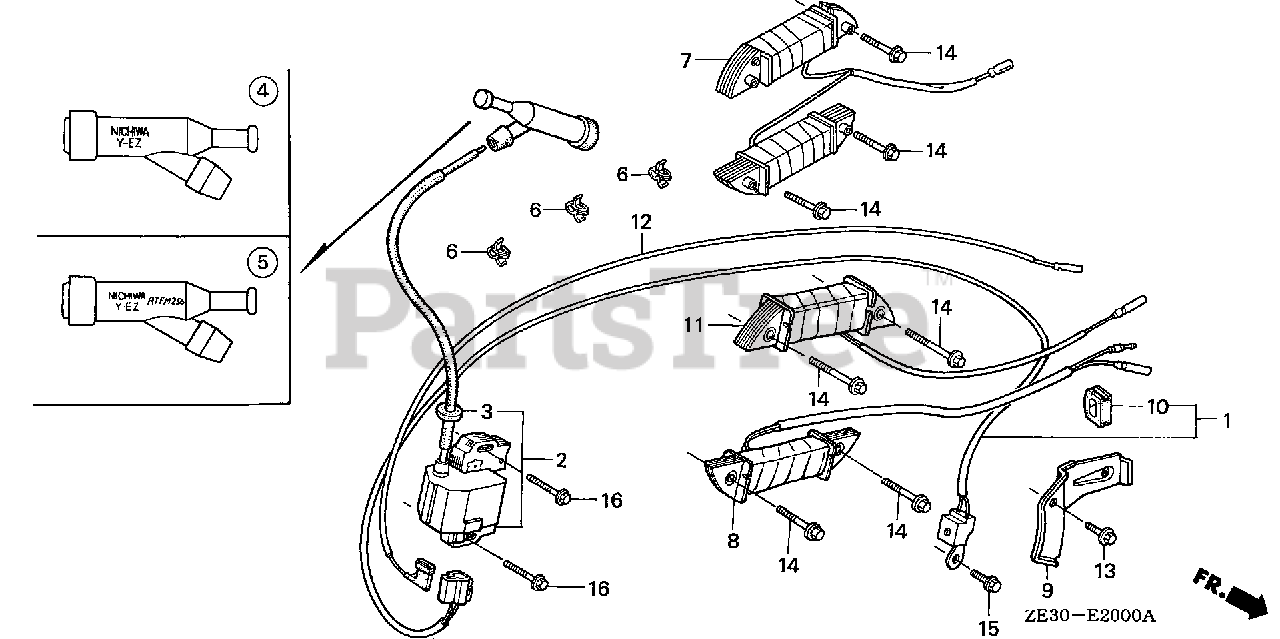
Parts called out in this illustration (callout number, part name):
1	COIL, PULSER
2	COIL ASSY., IGNITION
3	GROMMET, IGNITION WIRE
5	CAP ASSY., NOISE SUPPRESSOR (NICHIWA Y-EZ RTFM256)
6	CLIP, IGNITION WIRE (8MM)
10	GROMMET, PULSER WIRE
12	WIRE, STOP SWITCH
15	BOLT, FLANGE (6X14) (CT200)
16	BOLT, FLANGE (6X28) (CT200)
